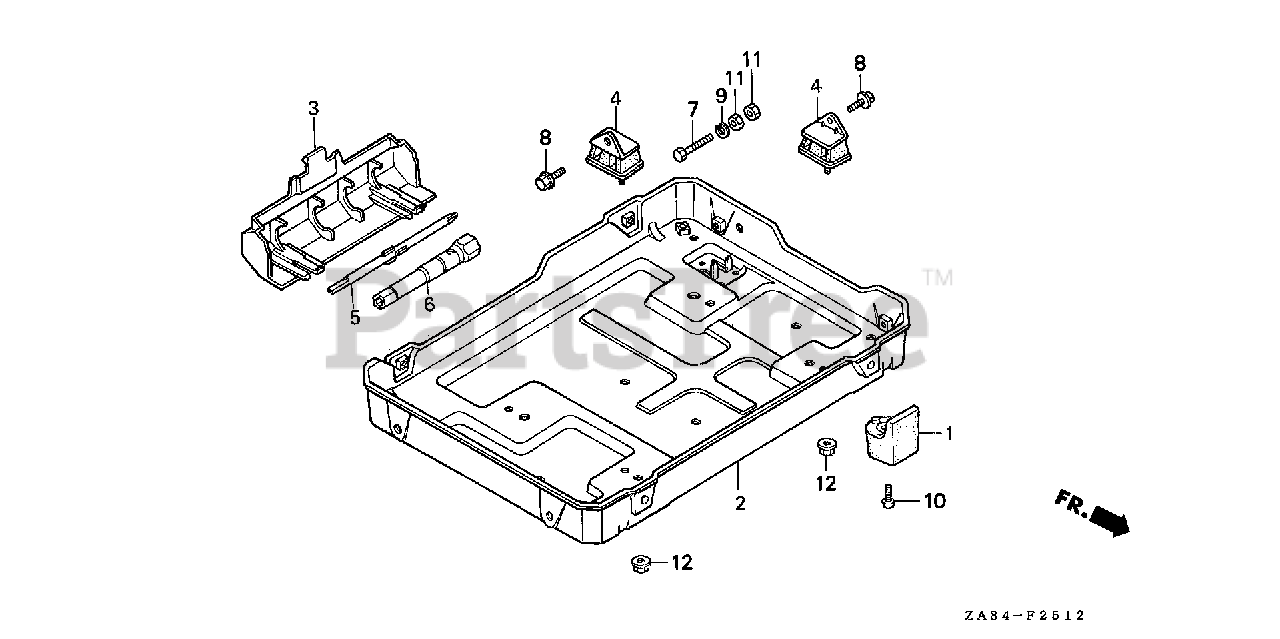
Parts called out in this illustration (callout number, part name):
1	RUBBER (LOWER)
2	COVER (LOWER)
3	COVER, TOOL HOLDING
4	RUBBER, SETTING
6	WRENCH, BOX (P19X10) (NOT AVAILABLE)
7	BOLT, HEX. (6X20)
7	BOLT, HEX. (6X22)
8	BOLT, FLANGE (6X12) (CT200)
9	WASHER, SPRING (6MM)
10	SCREW, PAN (6X10)
11	NUT, HEX. (6MM)
12	NUT, FLANGE (6MM)
